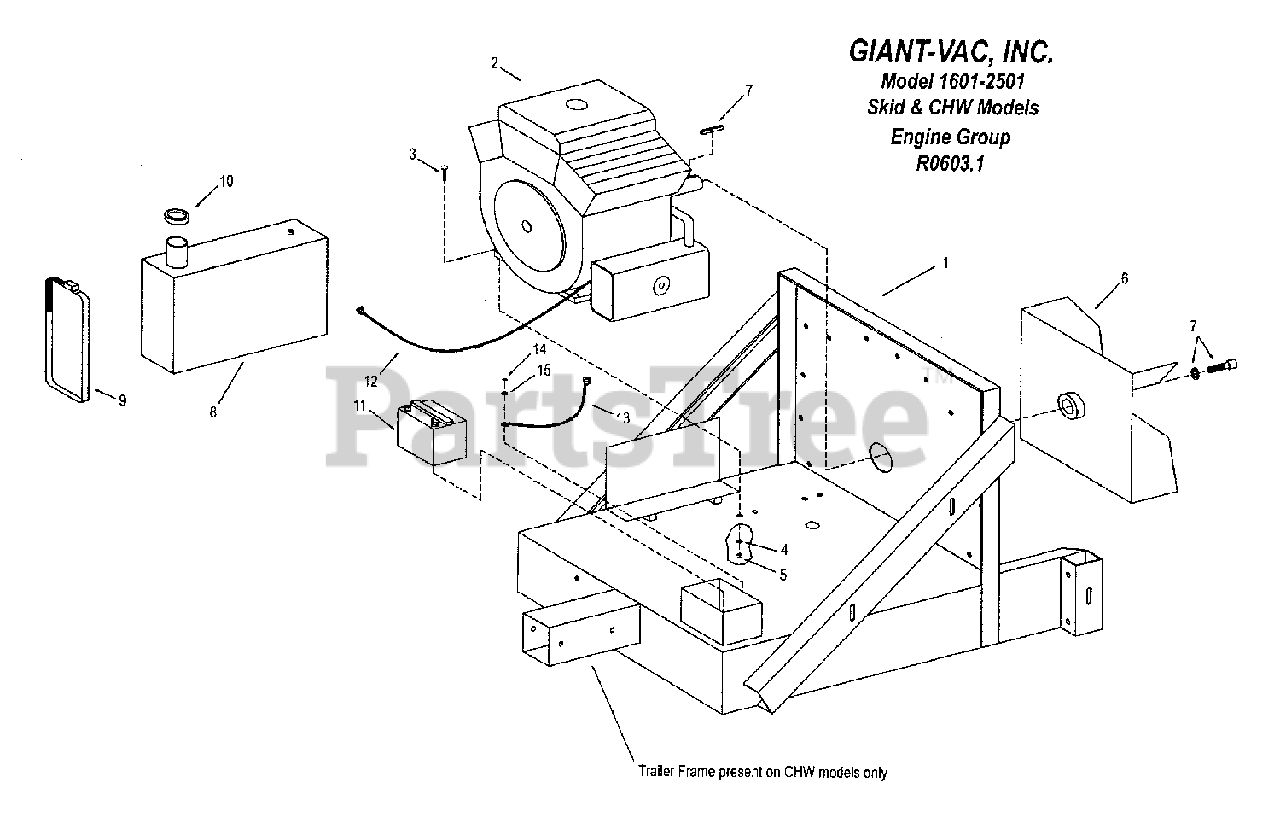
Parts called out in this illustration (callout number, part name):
1	Engine base (16018KID)
1	Engine base & Trailer frame (1601 CHW)
1	Engine base (1901/25018KID)
1	Engine base & Trailer frame (1901/2501 CHW)
2	* 16HP Briggs & Stratton Vanguard Engine
2	* 20HP Kohler Command Engine
2	* 25HP Kohler Command Engine
3	5/16 x 1-1/2" Hex bolt (Motor mount bolt)
3	3/8 x 2" Hex bolt (Motor mount bolt)
3	3/8 x 1-3/4" Hex bolt (Motof mount bolt)
4	5/16 Lock washer
4	3/8 Lock washer
5	5/16 Hex nut
5	3/8 Hex nut
6	Impeller
7	7/16-20 x 2" Impeller bolt and key group
7	5/8-18 x 2" Impeller bolt & key group
8	Fuel tank
9	Fuel tank strap
10	Fuel tank cap
12	Battery cable -3288 (positive)
13	Battery cable -1688 (ground)
14	3/8 Hex nut (secures ground cable to engine base)
15	3/8 Lock washer
